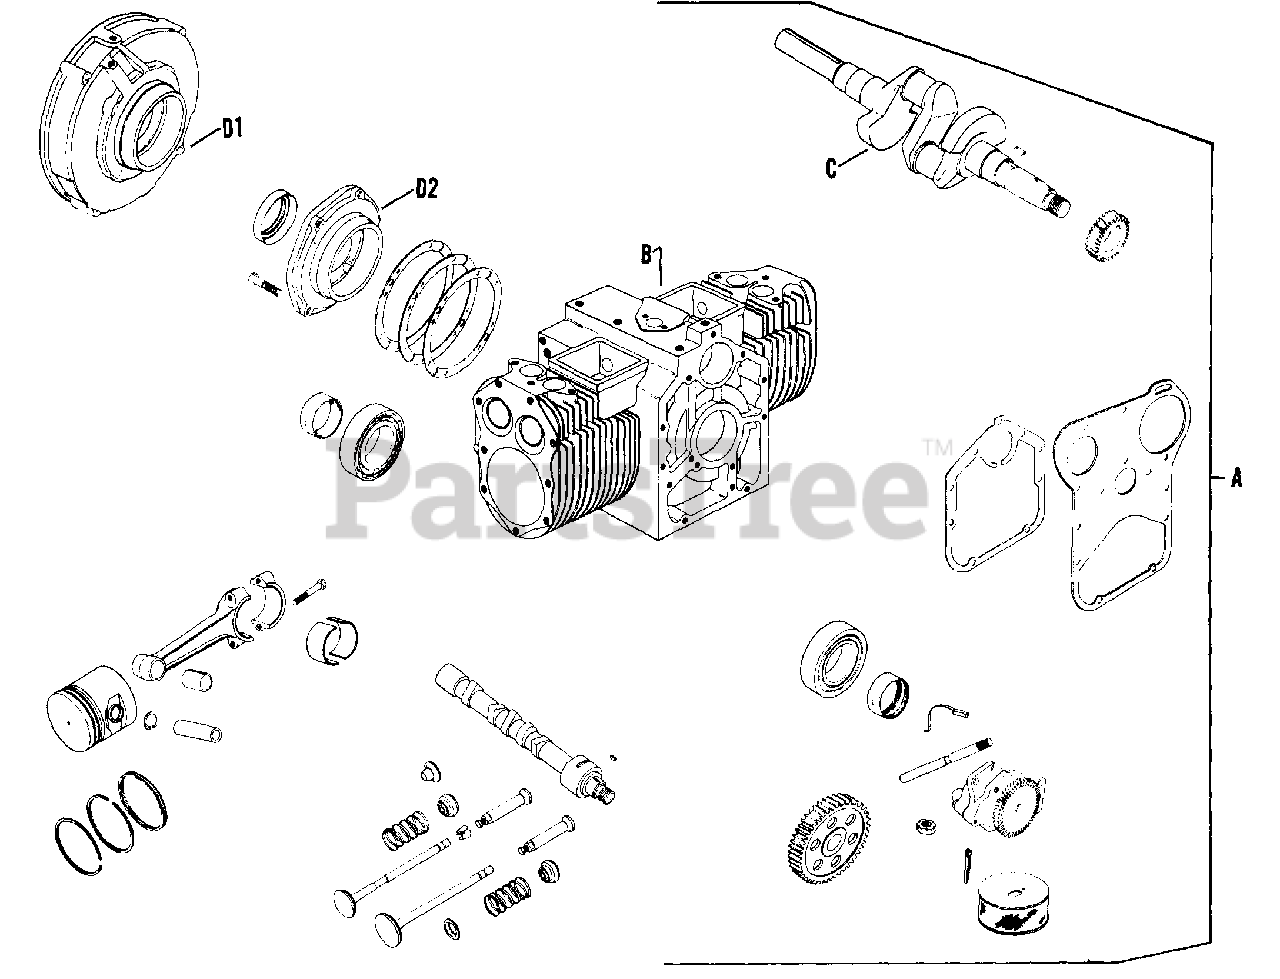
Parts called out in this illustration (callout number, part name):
A	SHORT BLOCK - USE B-271413
B	BLOCK - USE 49 005 01
C	CRANKSHAFT - DISCONTINUED
